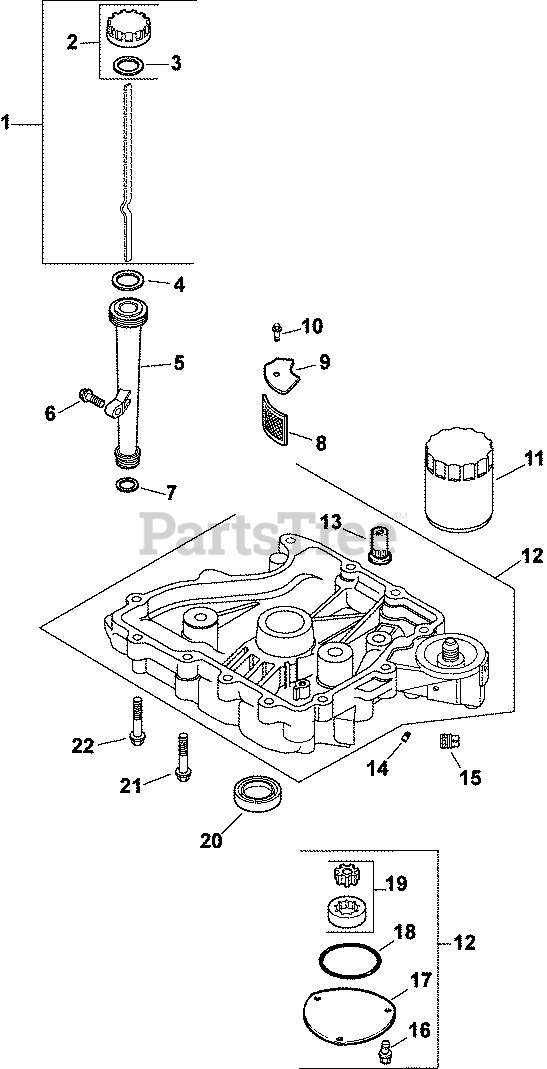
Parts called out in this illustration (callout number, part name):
1	DIPSTICK/CAP ASSY (YELLOW) - DISCONTINUED
2	KIT, OIL FILL CAP (YELLOW)
3	O-RING, DIPSTICK
4	O-RING, UPPER OIL FILL TUBE
5	TUBE, OIL FILL USE 25 123 07-S
6	SCREW,FLG THD FRM M6X1.0X25-(#25086395S)
7	O-RING, LOWER OIL FILL TUBE
8	SCREEN, OIL-USE 24 162 26-S
10	SCREW,FLG THD FRM M5X0.8X16-(#25086398S)
11	OIL FILTER
12	PAN, OIL
13	VALVE, OIL PRESSURE RELIEF
14	PLUG, PIPE 1/8 NPTF-SQ.HD.
15	PLUG, SQ HD PIPE 3/8"
16	SCREW,FLG THD FRM M5X0.8X16-(#25086398S)
17	COVER, OIL PUMP
18	O-RING (2.5" DIA)
19	PUMP ASSEMBLY, OIL - DISCONTINUED
20	SEAL, OIL
21	SCREW, HEX FLANGE -USE 24 086 17-S
22	SCREW, FLG M8X1.25X45
